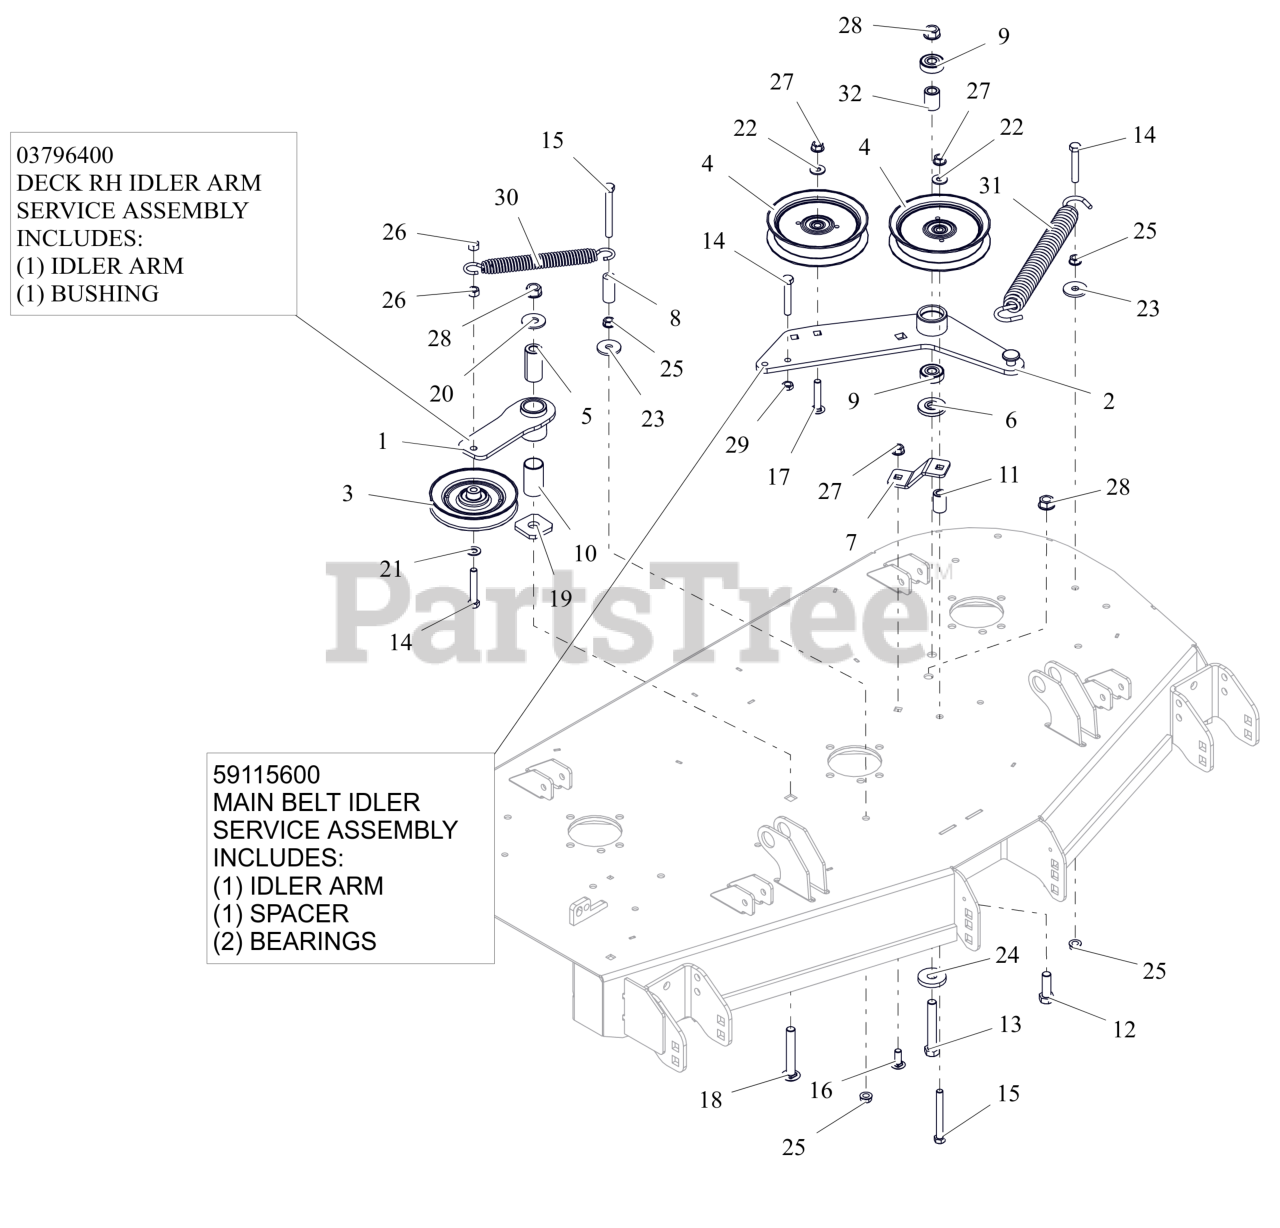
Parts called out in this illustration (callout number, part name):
1	WMT, IDLER ARM - BLACK
1	ASSEMBLY, MAIN BELT IDLER
2	WLDMT, DECK PTO IDLR ARM
2	ASM, IDLER ARM (DECK)
3	IDLER, V-5.00"
4	IDLER, FLAT 5.00"
5	BSHG, SPCR .502X.997X2.03 PM
6	SPACER, IDLER ARM
7	PTO FIXED IDLER MTG BRKT -RED
8	HOSE, .38 X 1.65
9	BRG-BALL .500X1.38X.437
10	BSHG, 1.00X1.125X1.937
11	BUSHING, SLV .380X.750X1.190
12	BLT,HEX .50-13X1.50 G5 ZCC
13	BLT,HEX .50-13X3.25 G5 ZCC
14	BLT,HEX .38-16X2.25 G5 ZCC
15	BLT, HEX .38-16X3.25 G5 ZCC
16	BLT,RHSSN .38-16X1.00 G5 ZCC
17	BLT,RHSSN.375-16X2.00 G5 ZCC
18	BTL,RHSSN .500-13 X 3.25 G5 ZCC
19	WSHR-FLT .640X1.75X.250
20	WSHR,FLT .563X1.375X.109 ZCC
21	WSHR,FLT .406X.812X.065 ZCC
22	WSHR,FLT .375X.875X.083 ZCC
23	WSHR,FLT .406X1.375X.135 ZCC
24	WSHR-FL-STL 0.557X1.625X0.25 ZCC
25	NUT, SPNLK-FLG .38-16 G5 ZCC
26	NUT-LK-CTR .38-16 ZC120
27	NUT-LK-CTR-FLG .375-16 GF ZCC
28	NUT-LK-CTR-FLG .500-13 GG ZCC
29	NUT-JAM .375-16 G2 ZCC
30	SPRING, EXTENSION
31	SPRING, EXTENSION
32	SPACER .510 X .75 X 1.1485
